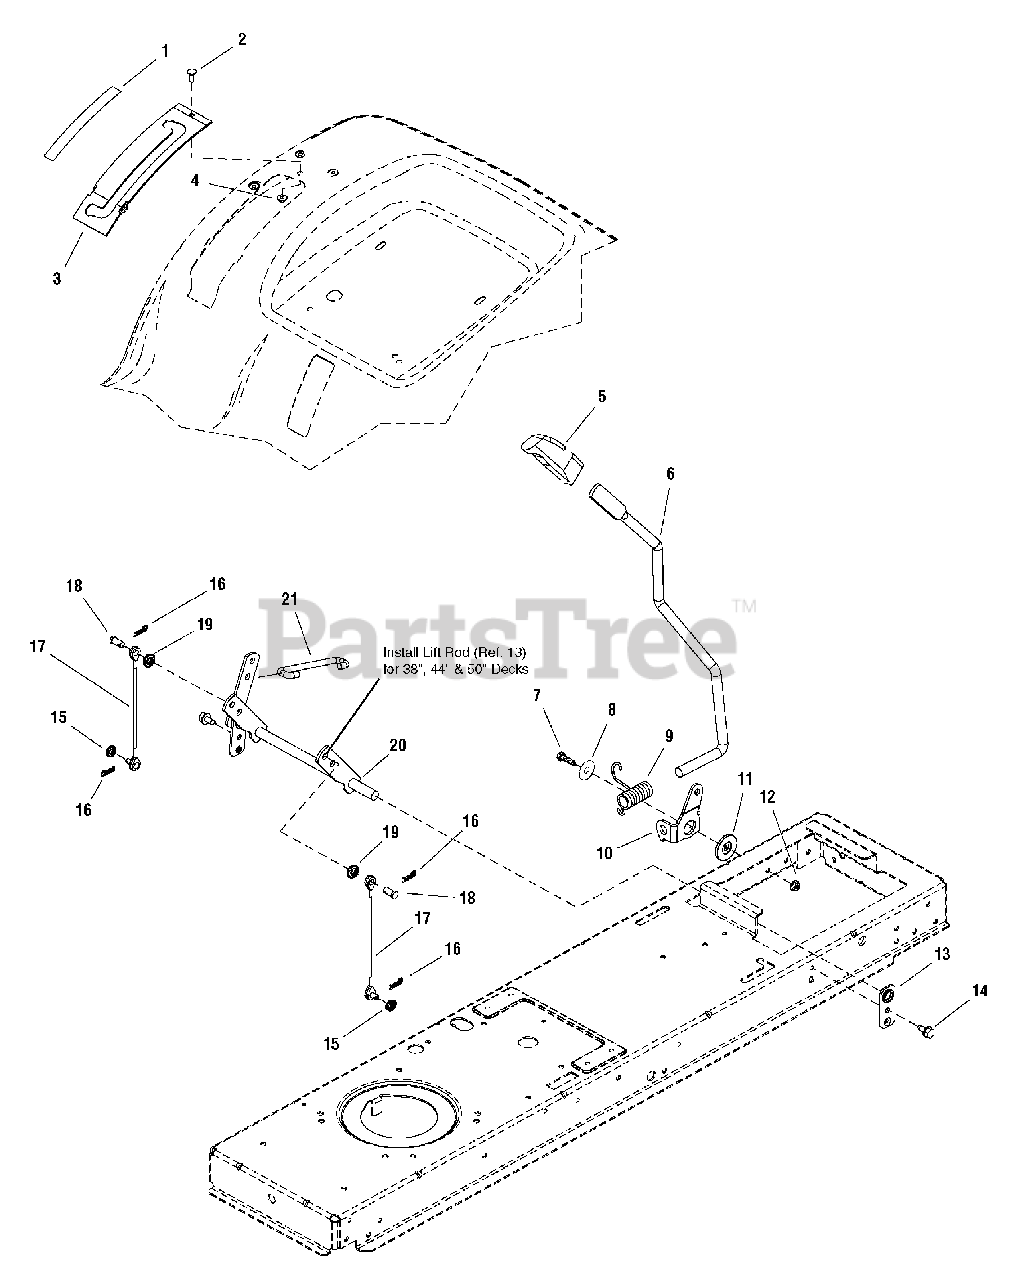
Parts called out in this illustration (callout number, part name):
1	DECAL, Mower Transport Lift
2	CARRIAGE BOLT, 1/4-20 x 5/8 G5
3	QUADRANT, Lift 12GA
4	NUT, Hex Flange Whiz, 1/4-20
5	GRIP
6	ROD, Lift Handle E-Coat, 17.7 LG
7	CAPSCREW, Hex Head, 5/16-18 x 1
8	WASHER, Plain, 21/64 x 1-1/4
9	SPRING, Torsion, 2.12 LG Black
10	CLEVIS, Lift 7GA
11	SPACER, Pivot 0.330ID 1.76OD .37TH Powdered Metal
12	NUT, Hex, Flange Whizlock, 5/16-18
13	PLATE, Bearing
14	SCREW, Taptite, 5/16-18 x 5/8
15	WASHER, Flat, 5/16
16	CLIP, Spring
17	CABLE, Lift Ring Terminals
18	PIN, Clevis
19	WASHER, 3/8
20	SHAFT ASSEMBLY, Lift
21	ROD, Lift, 5.43 LG
